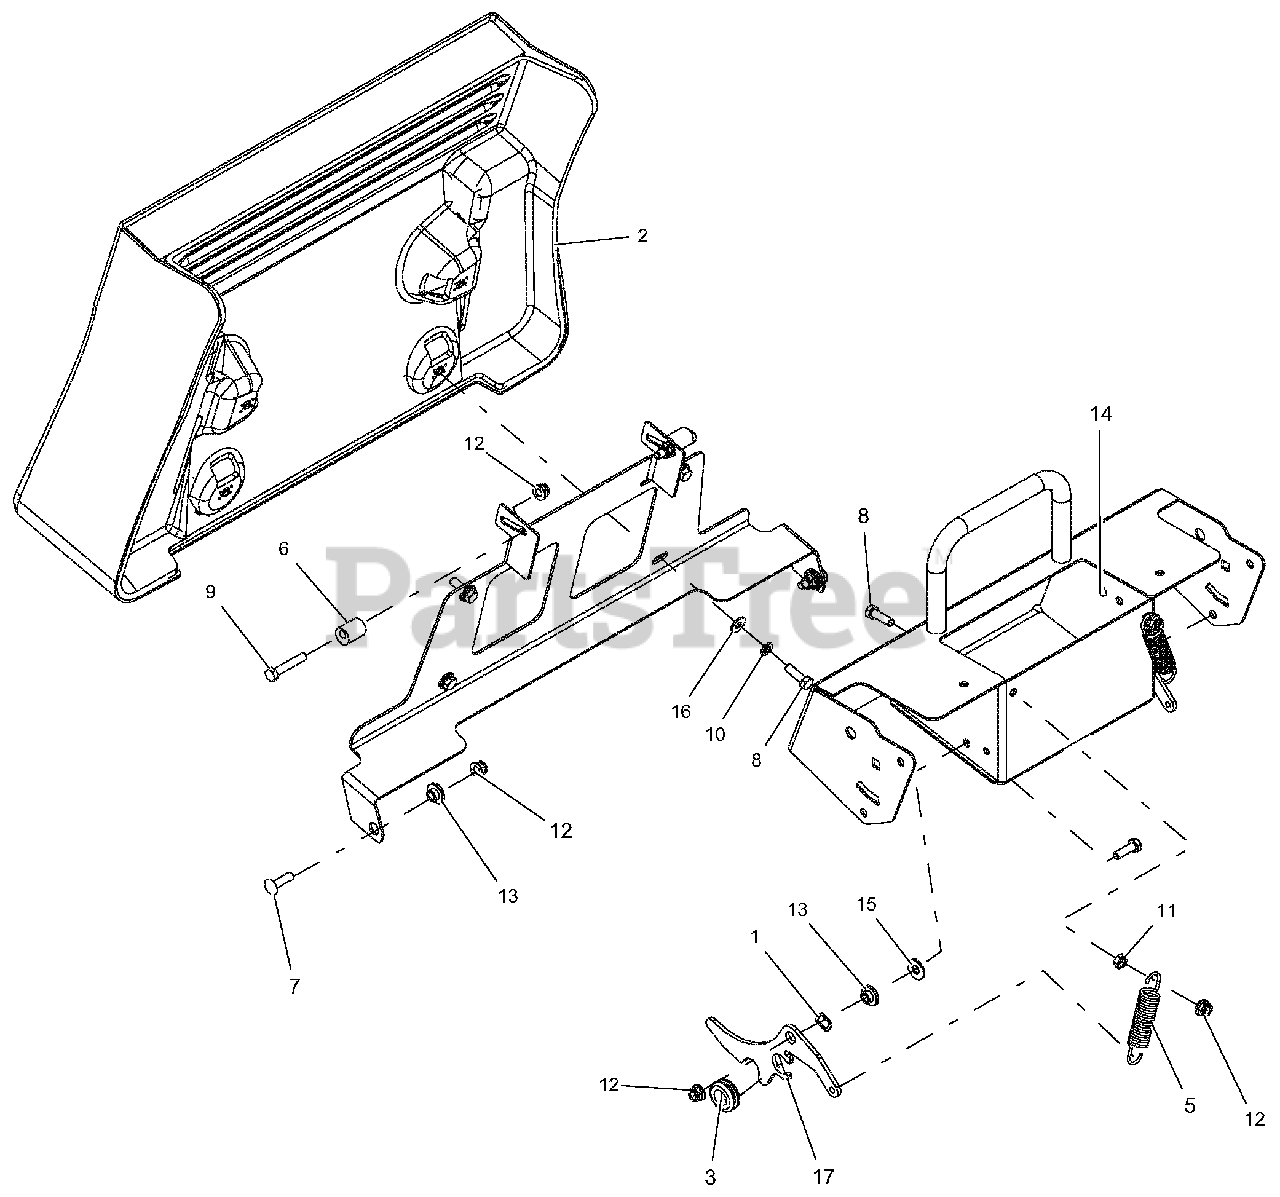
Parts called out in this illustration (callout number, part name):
1	WAVE WASHER .531X.781X.125 FH
2	PAD, PROSTANCE
3	GROMMET, SPLIT RUBBER
5	SPRG, EXTENSION
6	ECCENTRIC
7	BLT-RDHDSQSHNK .31-18X1.125 G5YWZC
8	BLT-HEX .31-18X1.00 GR5 YWZC
9	BLT-HEX .31-18X1.75 GR5 YWZC
10	WSHR-LK .31X.078 REG YWZC
11	@ NUT-LK-CTR-JAM .31-18 YWZ C
12	NUT-LK-NYL-FLG .31-18 YWZC
13	BSHG, FLG .32X.500.344X.880
14	WLDMT, CONTROL PANEL, PRO-STANCE
15	WSHR-FL-STL.38X.875X.083 YWZC
16	WSHR-FL-STL.312X.734X.065 YW Z
17	LATCH, PAD MOUNT
